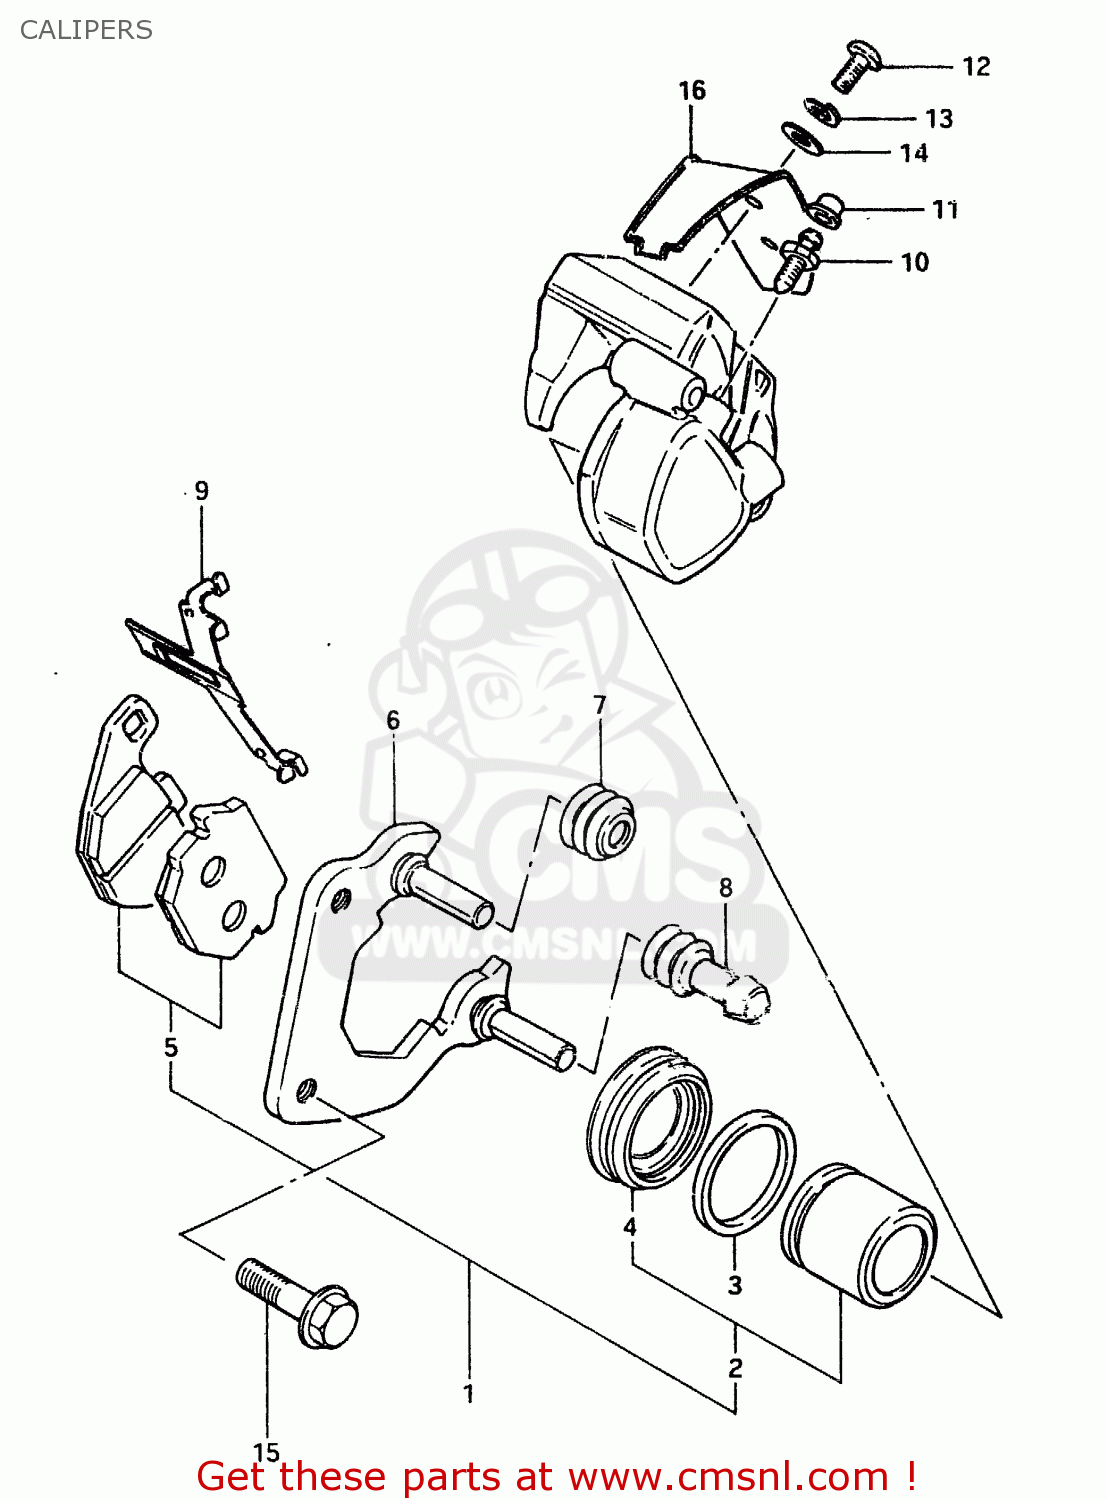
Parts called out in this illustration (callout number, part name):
1	CALIPERS ASSY
2	PISTON SET
3	SEAL,PISTON
4	BOOT,PISTON
5	PAD SET,BRAKE (MCA)
6	CARRIER,CALIPE
7	BOOT,AXLE
8	INSULATOR,AXLE
9	SPRING,PAD
10	BLEEDER
11	CAP,BREATHER
12	SCREW
13	LOCK WASHER
14	WASHER
15	BOLT
16	COVER
